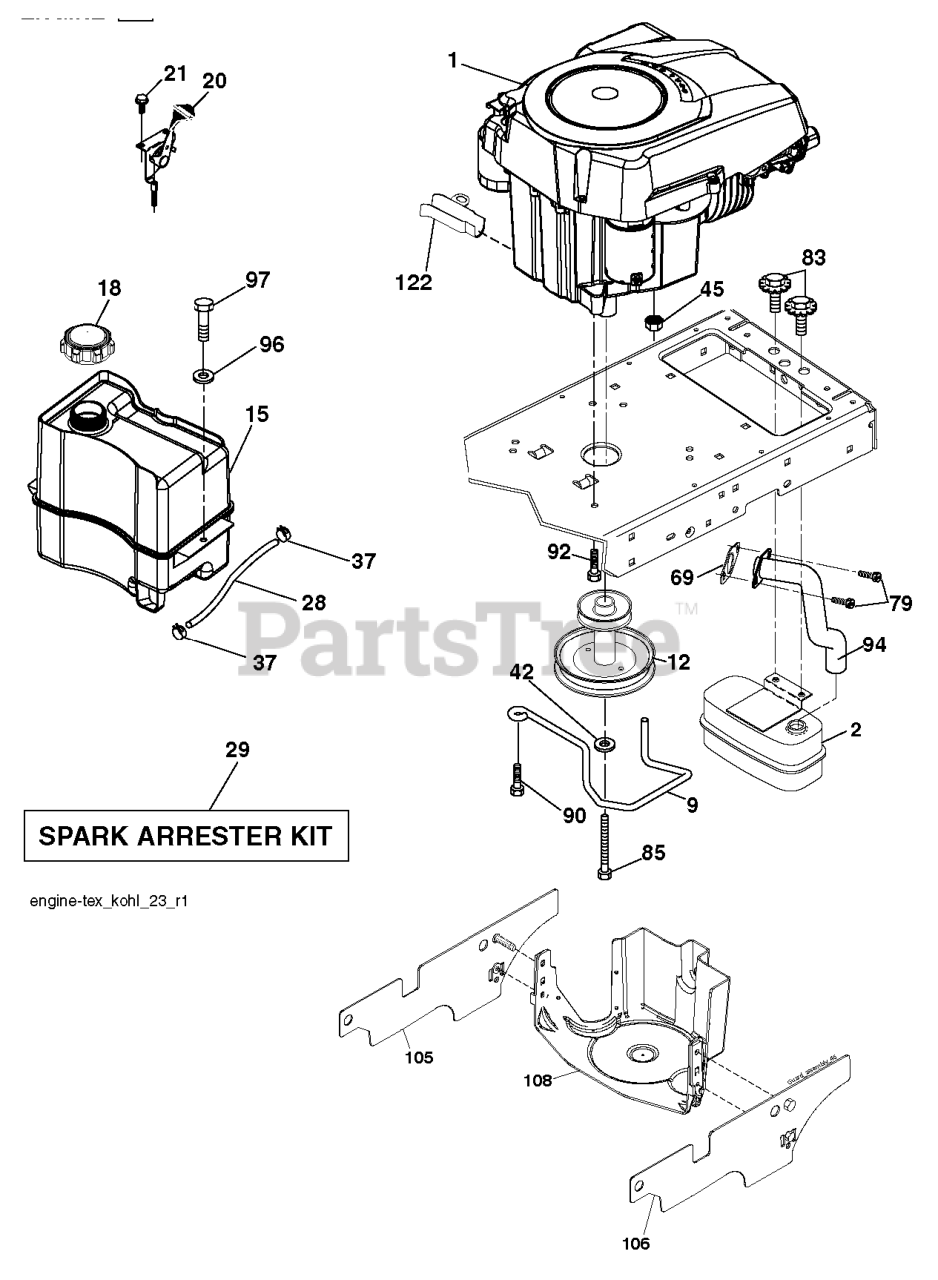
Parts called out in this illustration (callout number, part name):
2	MUFFLER.SINGLE.CYL.KOHL/B&S
9	KEEPER.BELT.ENGINE.4.2
12	PULLY ENGINE
15	RP TANK FUEL FRT 1.5 GAL
18	CAP.FUEL.2.25"VENTED"
20	CONTROL.TH/CK.C.
21	SCREW.#10 X 0.750.BOS
28	LINE.FUEL.20
29	KIT.SPARK ARRESTOR 794945 B&S
37	HOSE CLAMP
42	LOCKWASHER
45	NUT
69	GASKET.EXHAUST.KOHLER
79	SCREW.SOCKET HD.5/16-1
83	BOLT.5/16-18UNCX3/4 W/SEMS.BLK
85	BOLT HEX 7/16-20X4-1/4"
90	SCREW 3/8-16X1
92	SCREW 3/8-16X1
94	RP.TUBE.EXHAUST.KOHL.COURAGE
97	SCREW HEXWSHR 1/4-20X3/4
108	ENGINE COVER
122	EXTENSION DRAIN OIL
